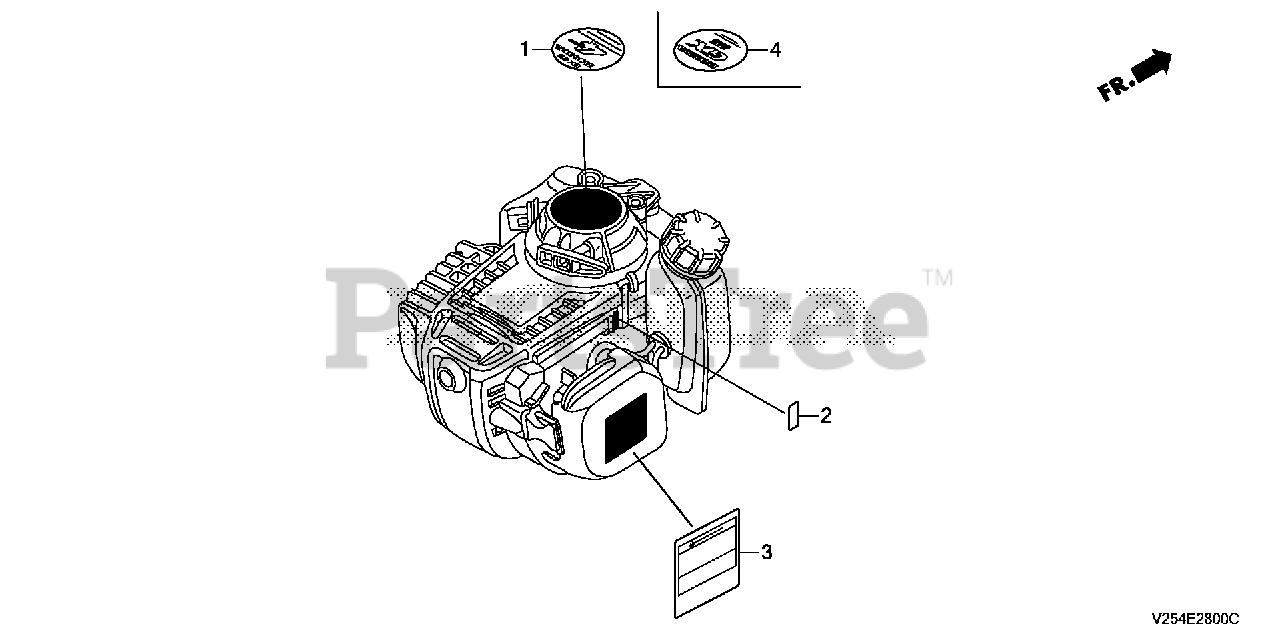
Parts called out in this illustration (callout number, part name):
2	MARK, TYPE (FY1)
3	MARK, OPERATOR CAUTION (ENGLISH)
4	MARK, EMBLEM
